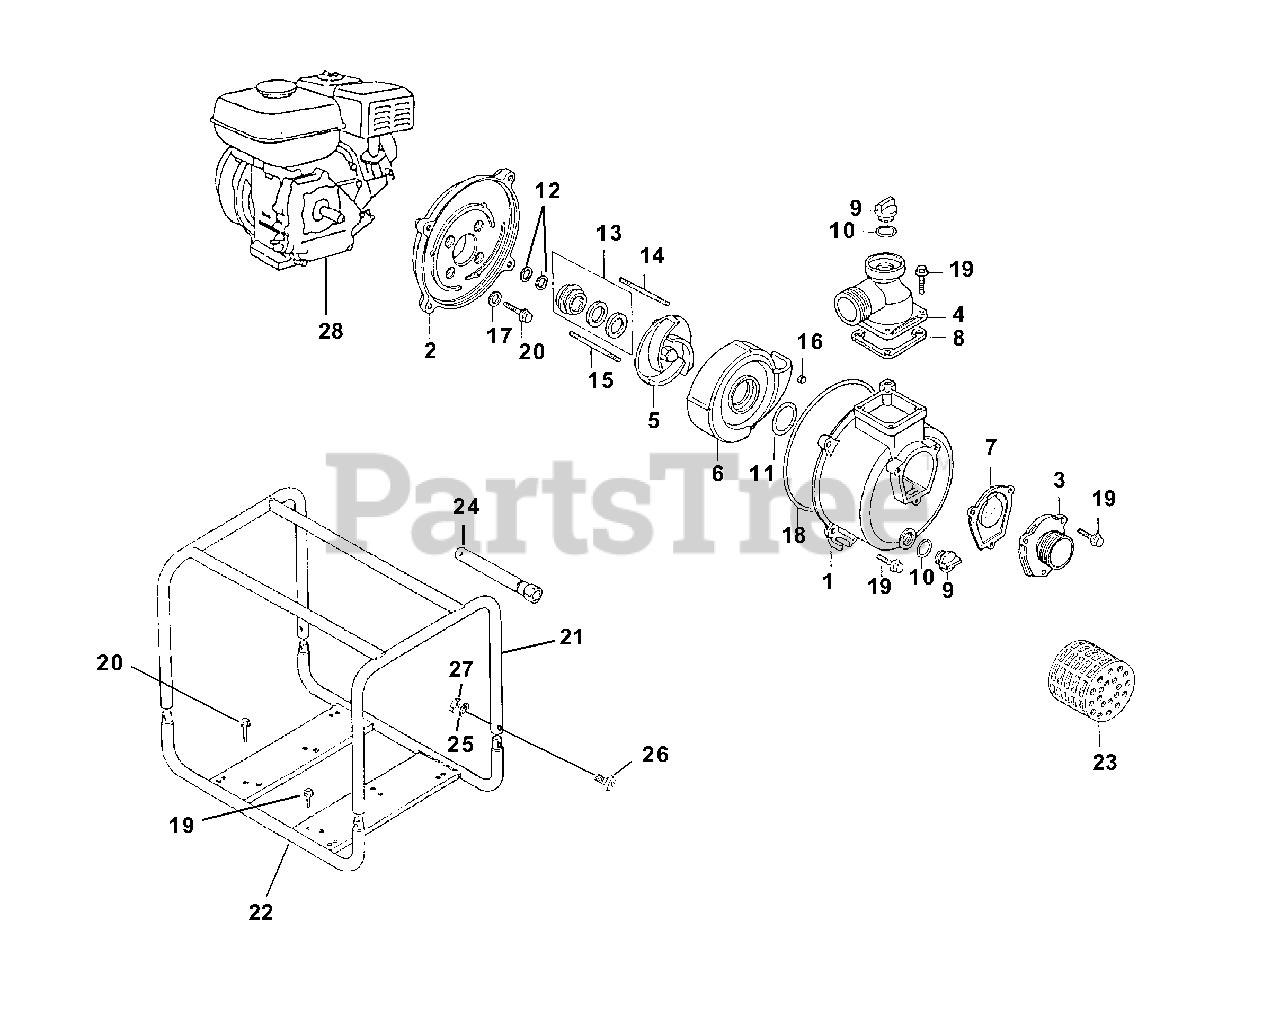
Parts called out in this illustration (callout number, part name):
2	Cover, Casing
3	Inlet Pipe 2" NPT
4	Outlet Pipe 2" NPT
5	Impeller
6	Case, Volute
7	Check Valve, Inlet
8	Packing, Outlet
9	Cap, Filler
10	Ring, Seal
11	O-Ring 49 x 5.7
12	Shim, Adjuster
13	Seal, Mechanical
14	Stud, Threaded 6 x 50
15	Stud, Threaded 6 x 50
16	Nut, 6mm
17	Washer, 8mm
18	Seal Ring, Casing
19	Bolt, Flanged 8 x 25
20	Bolt, Flanged 8 x 28
21	Upper Frame
22	Lower Frame
23	Strainer 2" NPT Female
24	Wrench, Spark Plug
26	Screw, Truss Hd. 8 x 30
27	Nut, Hex 8mm
